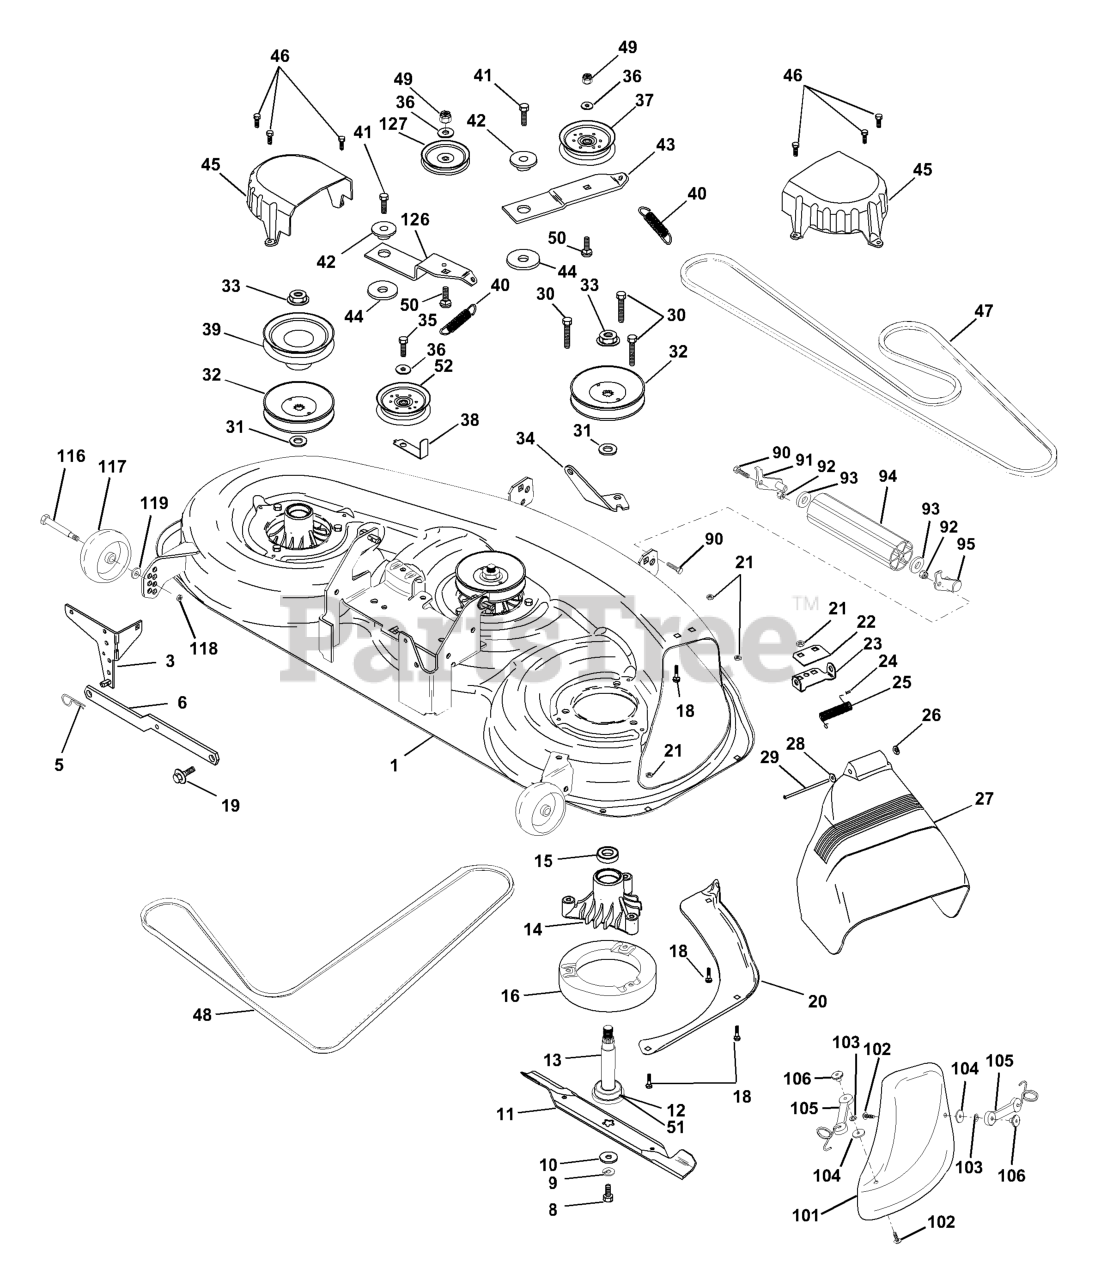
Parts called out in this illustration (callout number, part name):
1	HOUSING MOWER
3	BRACKET SWAY BAR
5	RETAINER-SPRNG RB
6	REAR SUSP ARM
8	BLADE BOLT
9	LOCKWASHER
10	WASHER.BLADE
11	MULCH BLADE 46"
12	BEARING.BALL.#6204.(MANDREL)
13	SHAFT.ASM.W/BEARING
14	HOUSING.MANDREL.44/46" VENT
16	STRIPPER
18	BOLT
19	BOLT SHD 5/16-18
20	BAFFLE, VORTEX MOWER 46"
21	LOCKNUT
22	STIFFENER BRACKET
23	DEFLECTOR BRACKET
24	CAP-SLEEVE LT
25	SPRING TORSION
26	NUT PUSH M
27	SHIELD, DEFLECTOR MOWER
28	Washer 11/32 x 5/8 x 16 Ga.
29	ROD.HINGE
30	SCREW
31	WASHER
32	PULLEY, MANDREL
33	NUT
34	ANCHOR, SPRING DECK 46"
35	SCREW LT
36	WASHER
38	KEEPER
39	PULLEY.DRIVEN.DECK.46"
40	SPRING.SEC.44"VEN
41	SCREW
42	SPACER RETAINER
43	ARM IDLER DECK 46"
44	HARDENED WASHER
45	COVER MANDREL 46
46	SCREW.1/4-20X5/8
47	BELT V SECONDARY
48	V-BELT PRIMARY 50"
50	BOLT.3/8-16X1.50
51	WASHER FELT
52	PULLEY IDLER FLAT 46 PRI DRIVE
90	BOLT
91	BRACKET LH (A)
92	NUT
93	Washer 17/32 x 7/8 x 16 Ga.
94	NOSE ROLLER
95	BRACKET RH (B)
101	COVER.MULCH.46"3-BLADE.(2 2)
102	SCREW
103	LOCKWASHER #10
105	LATCH ASSEMBLY
106	WELDNUT
116	BOLT, SHOULDER
117	WHEEL GAGE DONUT
118	LOCKNUT
119	WASHER.5/16.FLAT.STE.STD.
126	ARM IDLER PRIM 46
127	PULLEY.IDLER.4.25
